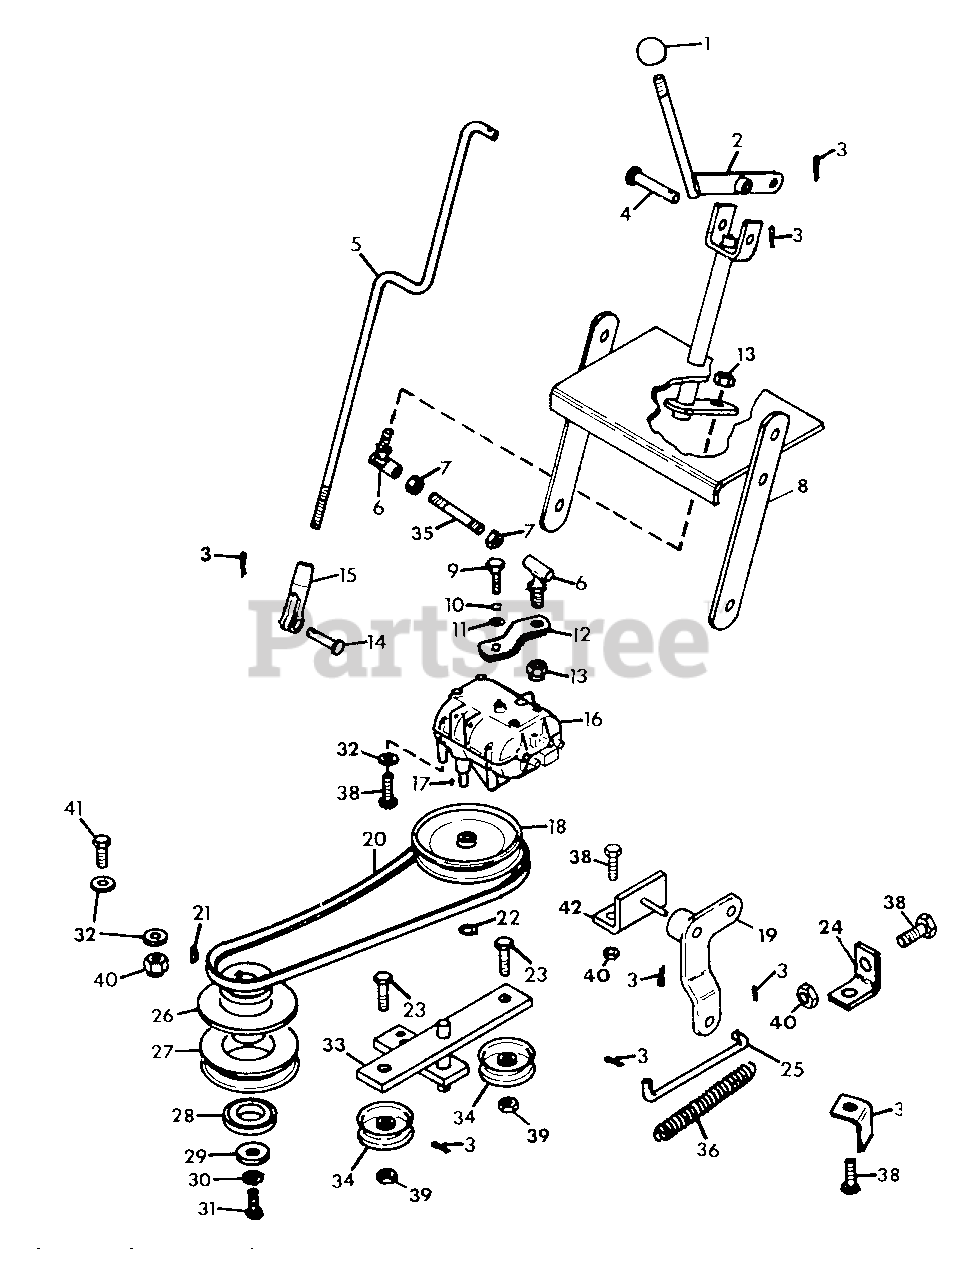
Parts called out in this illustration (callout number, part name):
1	Knob, Control
2	Weldment, Shift Lever
3	Pin, Cotter .09x.625
4	Pin, Clevis
5	Rod, Neutral Clutch
6	Ball Joint, Disconnecting
7	Nut, Hex 1/4-28
8	Weldment, Shifter
9	Bolt, Hex 1/4-28x.50
10	Washer, Lock 1/4
11	Washer, Flat .281x.625x.065
12	Arm, Trans. Shift
13	Nut, Lock 1/4-28
14	Pin, Clevis .312x.812
15	Clevis, 3/8-24
16	Transmission, 5-Speed
17	Key, Woodruff .187x.750 Hard
18	Sheave, Transmission
19	Lever, Clutch Pivot
20	Belt, Transmission
21	Key, Square .250x1.250
22	Ring, Retaining
23	Bolt, Hex 3/8-16xl.25
24	Tab, Spring
25	Rod, Clutch Idler Actuating
26	Weldment, Clutch Hub
27	Sheave, Mower Clutch
28	Bearing, Ball 1.574x3.149x.708
29	Washer, Special Flat
30	Washer, Lock 7/16
31	Bolt, Hex 7/16-20x2.00
32	Washer, Flat .344x.688x.065
33	Weldment, Clutch Idler Actuating
34	Sheave, Idler
35	Rod, Trans. Shifter
36	Spring, Neutral Clutch
37	Belt Guide, Transmission
38	Bolt, Hex 5/16-18x.75
39	Nut, Lock 3/8-16
40	Nut, Lock 5/16-18
41	Bolt, Hex 5/16-18xl.75
42	Weldment, Clutch Lever Bracket
